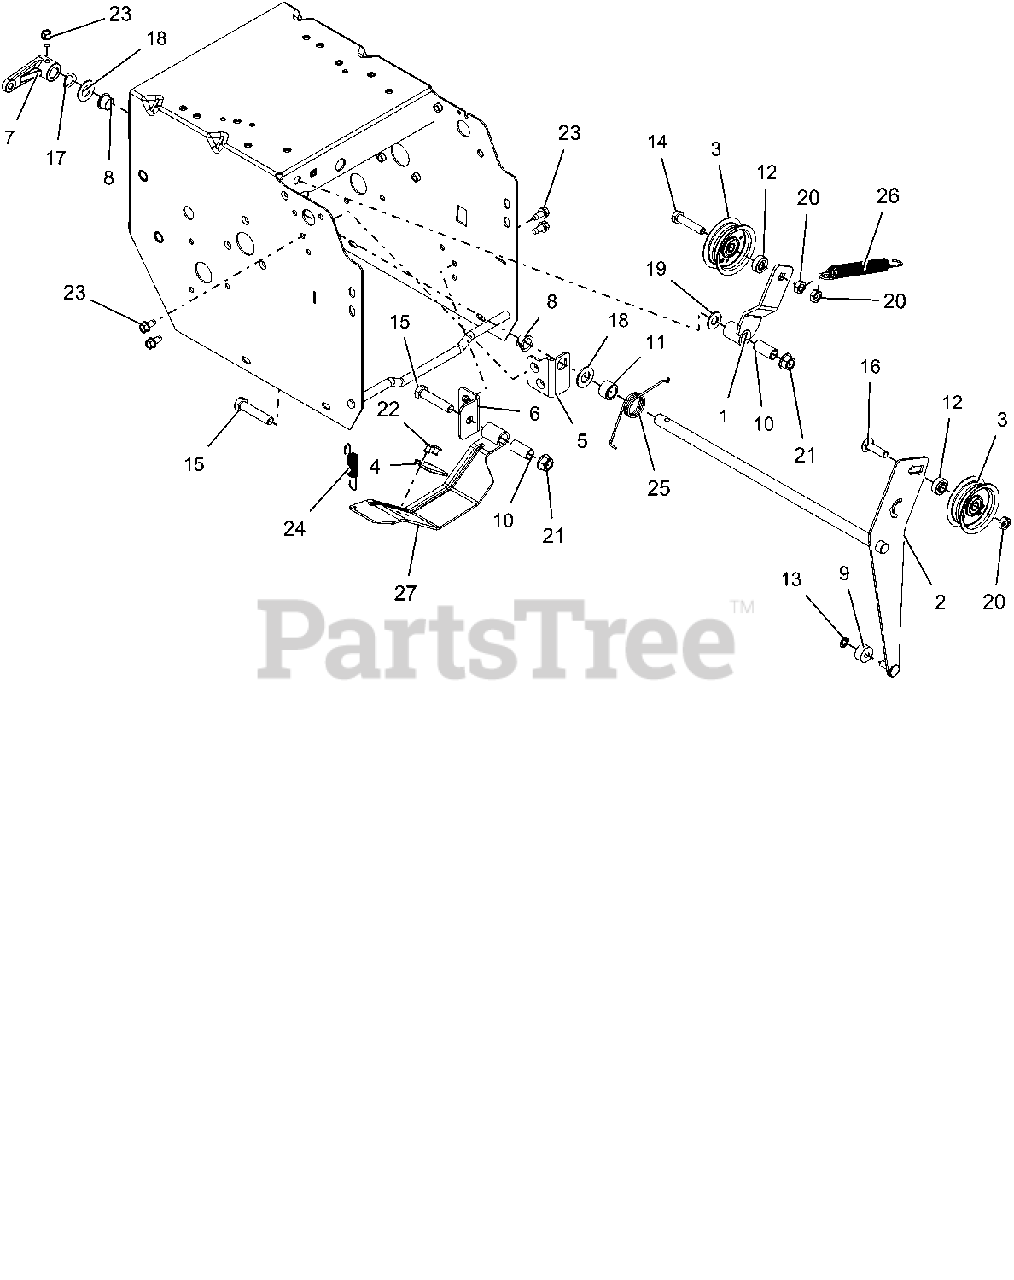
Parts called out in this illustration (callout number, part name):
1	WLDMT, TRACTION IDLER ARM
2	WLDMT, ATTACHMENT IDLER ARM
3	IDLER, FLAT - 2.00"
4	PAD, BRAKE
5	BRKT, MOUNT - IDLER ARM
6	BRKT, BRAKE MOUNT
7	ARM, CLUTCH - ATTACHMENT
8	BUSHING, POLYLINER - .50 SPLIT
9	BSHG, SLV .265 X .625 X .375
10	BSHG, SLV .385 X .500 X 1.045
11	BSHG, SLV .510 X .751 X .475
12	BSHG, FLG .315X.500X.358X.281
13	RG-RTNG-EXT .250 X .010
14	BLT-HEX .31-18X1.50 GR5 YWZC
15	BLT-HEX .38-16X1.75 GR5 YWZC
16	BLT-RDHDSQSHNK .31-18X1.125 G5YWZC
17	WSHR, WAVE .50X.75X.015 .13FRHT
18	WSHR-FL-STL .531X1.000X.063 YWZC
19	WSHR-FL-STL.406X.812X.065 YWZ
20	NUT-LK-CTR-JAM .31-18 YWZC
21	NUT, LK-TOP-FLG .38-16 YWZC
22	RVT-POP .187x.250 (#64) YWZC
23	SCR-TAP .25-20X.50 HWH TR YWZ
24	SPRG, EXTENSION
25	SPRG, TORSION
26	SPRG, EXTENSION
27	ARM, BRAKE W/PAD
